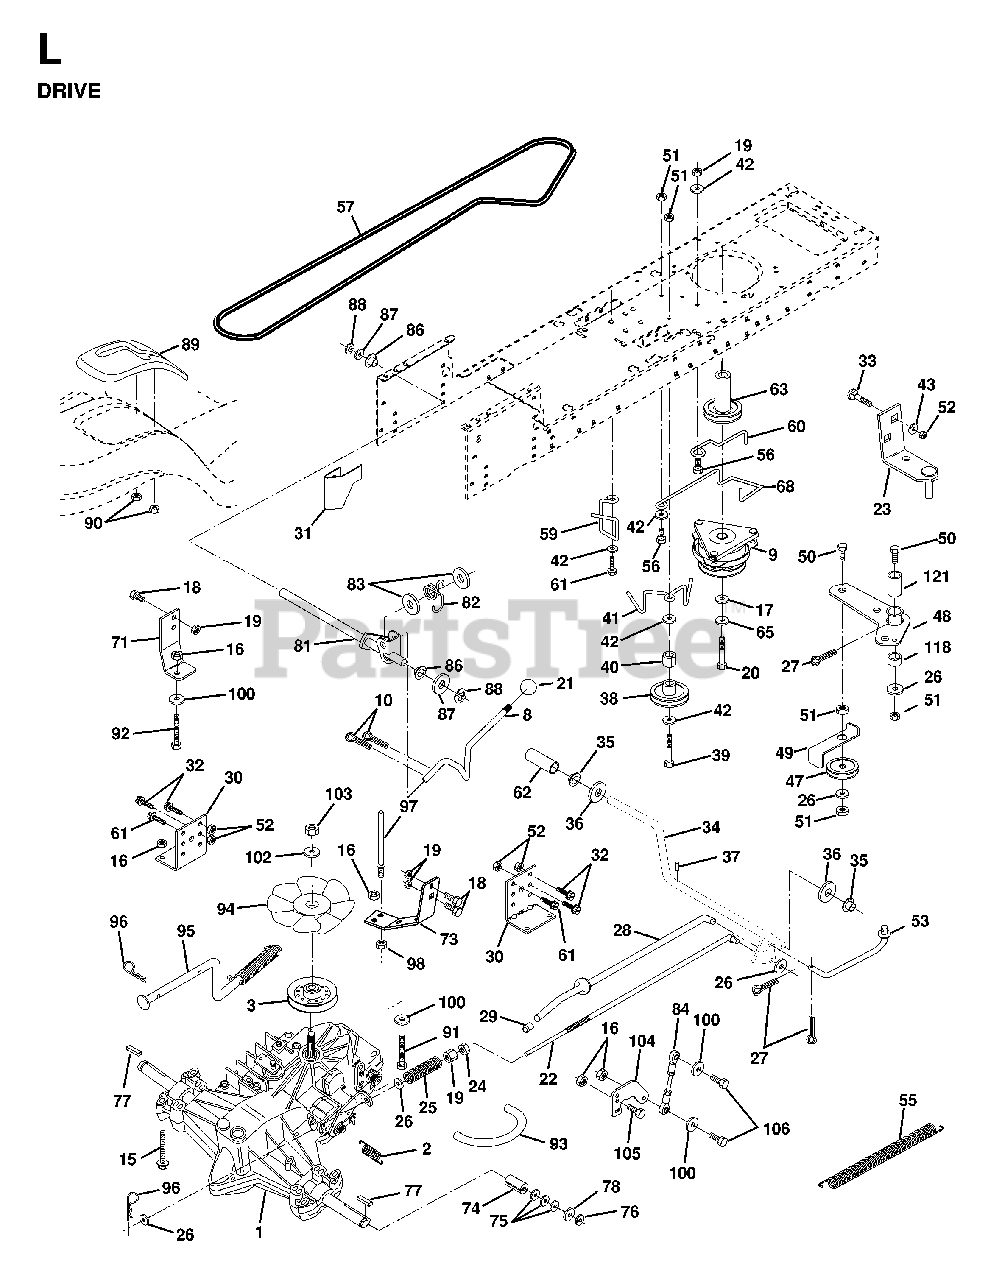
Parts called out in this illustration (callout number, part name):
1	TRANSAXLE ASSEMBLY
2	SPRING BRAKE
3	PULLEY, TRANSAXLE
8	ROD SHIFT FENDER
9	CLUTCH ELECT 1051B
10	PIN COTTER
15	BOLT HEX 5/16-18 GR 5
16	NUT.71038.31-18.HEX.NYLOCK
19	NUT
20	BOLT HEX
21	PISTOL KNOB
22	ROD BRAKE HYDRO
23	BRACKET ASM MTG
24	NUT
25	SPRING ROD LT
27	COTTER PIN
28	ROD BRAKE PARK LT
29	PLUNGER CAP
30	BRACKET TRANSAXLE
31	KEEPER BELT LH
32	BOLT
33	BOLT
34	SHAFT, FOOT PEDAL
35	BEARING.NYLON
36	WASHER LT
37	DRIVE PIN
38	PULLEY.IDLER.FLAT
41	KEEPER, BELT IDLER
42	WASHER
47	IDLER PULLEY
48	BELLCRANK ASSEMBLY
49	RETAIN BELT
50	BOLT
51	LOCKNUT
52	LOCKNUT
53	LINK, CLUTCH LT
55	SPRING, RETURN LT
59	KEEPER CENTER SPAN
61	SCREW
62	PEDAL COVER T
63	PULLEY CLU ELEC
65	LOCKWASHER
71	STRAP LH TORQUE
73	STRAP TORQUE RH HYDRO
74	SPACER SPLIT
76	E-RING LT
77	SQUARE KEY
81	SHAFT ASSY
82	SPRING,TORSION
83	WASHER
86	BUSHING.STEERING.ROD
88	KLIP RING
89	CONSOLE SHIFT
92	HEX BOLT
93	FUEL LINE
94	FAN 7" HYDRO
95	CONTROL ARM, BYPASS HYDRO
96	RETAINER M
97	KEEPER BELT RH
100	WASHER M
103	NUT.HEX.1/2-20
104	CONTROL ARM
106	BOLT.5/16-18X1-1/4 FULL.THREAD
118	SPACER BELLCRANK
121	NYLINER CLUTCHING
